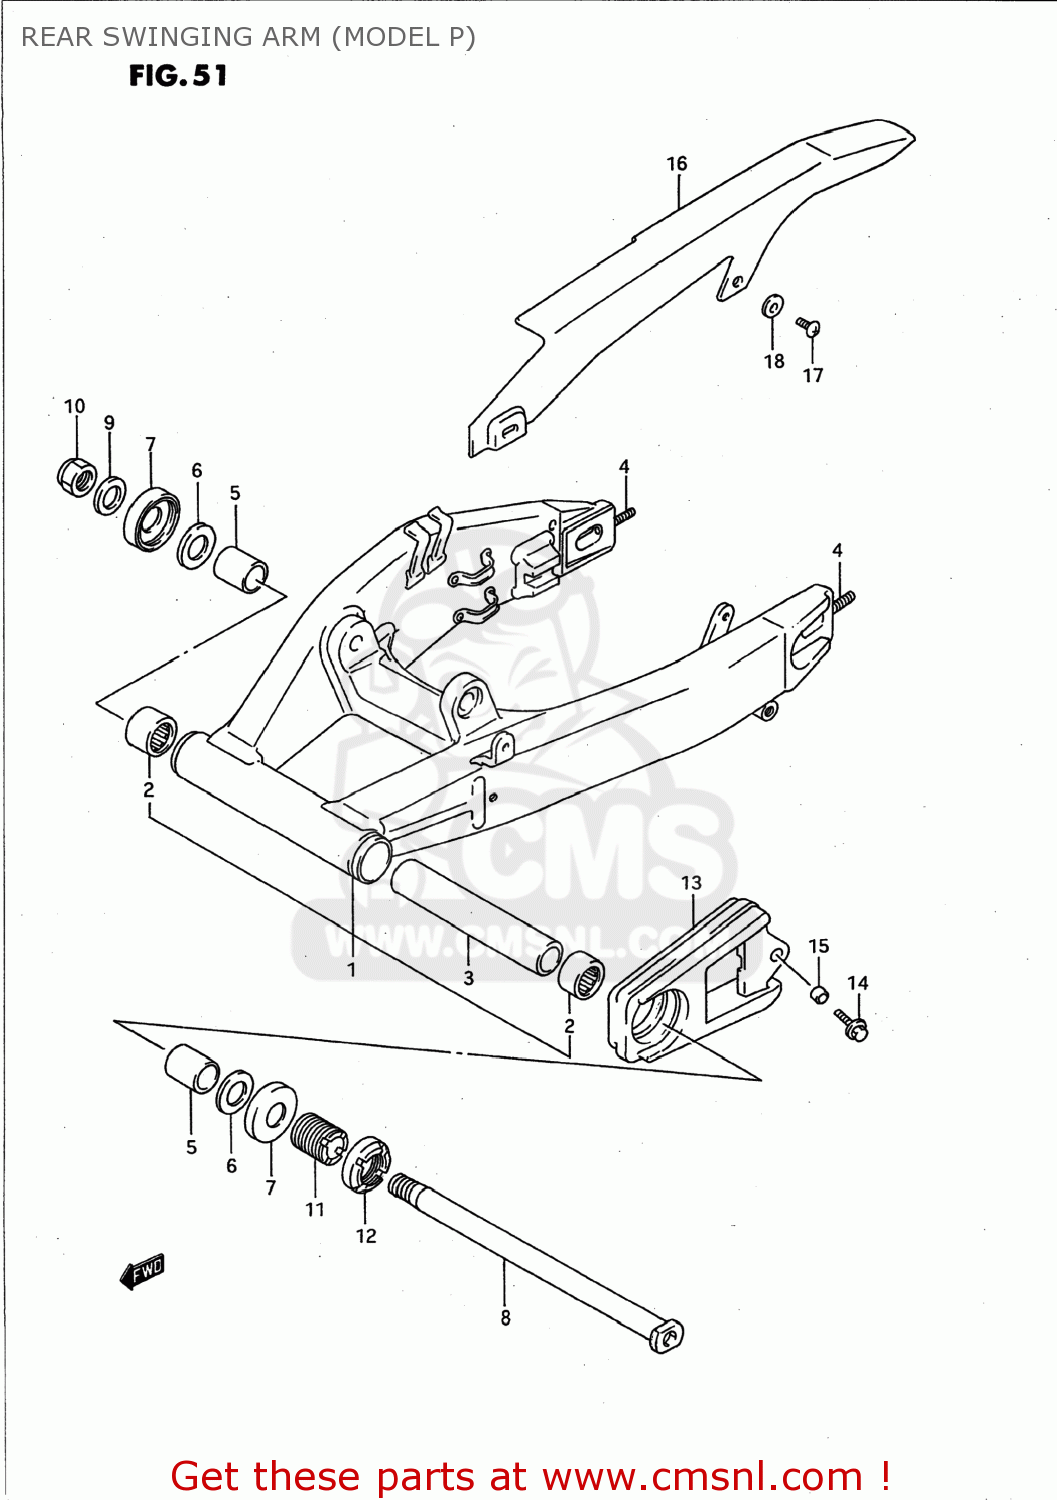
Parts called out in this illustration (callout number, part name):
1	SWINGINGARM ASSY,RR
2	BEARING(25X33X30)
3	SPACER,RR SWGARM PIVOT CTR
4	STUD,CHAIN ADJUSTER BOLT
5	SPACER,RR SWGARM PIVOT BERRING
6	WASHER
7	DUST SEAL,RR SWGARM PIVOT
8	SHAFT,REAR SWING ARM
9	WASHER
10	NUT
11	BOLT,RR SWGARM PIVOT
12	NUT,REAR SWING ARM PIVOT
13	BUFFER,CHAIN TOUCH DEFLECTOR
14	BOLT 6X20,WITH PLAIN WASHER
15	SPACER
16	CASE,CHAIN
17	SCREW
18	WASHER
